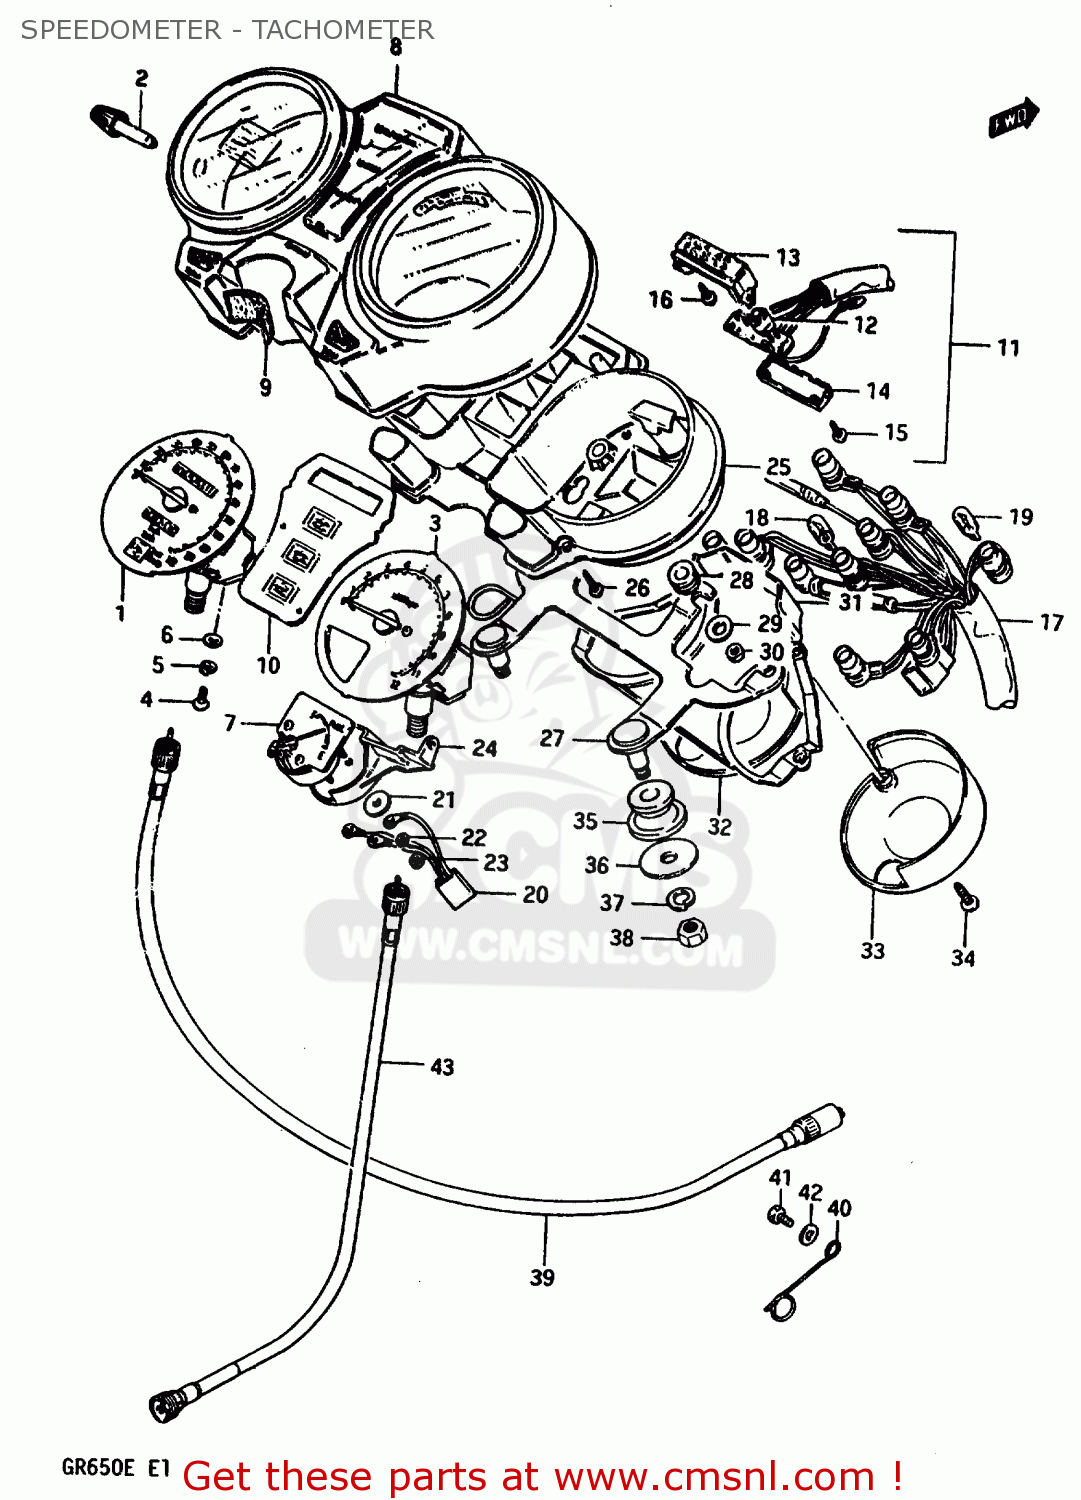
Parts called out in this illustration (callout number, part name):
1	SPEEDOMETER (KILO)
2	KNOB,TRIP
3	METER,TACHOMETER
4	SCREW 4X10
5	LOCK WASHER
6	WASHER
7	METER,FUEL
8	HOOD,METER
9	SEAL,IGNITION SWITCH
10	PLATE,PILOT BOX
11	INDICATOR ASSEMBLY,GEAR POSITION
12	BULB(14V1.12W)
13	CASE,GEAR INDICATOR
14	COVER,LWR
15	SCREW,GEAR INDICATOR
16	SCREW,INDICATOR
17	SOCKET
18	BULB(12V3.4W,T10)
19	BULB(12V1.7W,T10,WB121)
20	LEAD WIRE, FUELMETER
21	WASHER,FUEL METER
22	LOCK WASHER
23	NUT 3MM
24	BRACKET,FUEL METER
25	CASE,METER
26	SCREW,PILOT BOX
27	BRACKET,COMBINATION METER
28	CUSHION
29	WASHER (5.5X16X1.2)
30	NUT
31	COVER,LWR
32	COVER,METER,UNDER
33	COVER,METER UNDER
34	SCREW
35	CUSHION,METER BRACKET
36	WASHER (8.5X20X1.6)
37	LOCK WASHER
38	NUT
39	CABLE ASSY,SPEEDOMETER
40	CLAMP,SPEEDOMETER CABLE
41	BOLT, UPPER
42	WASHER
43	CABLE ASSEMBLY,TACHOMETER
